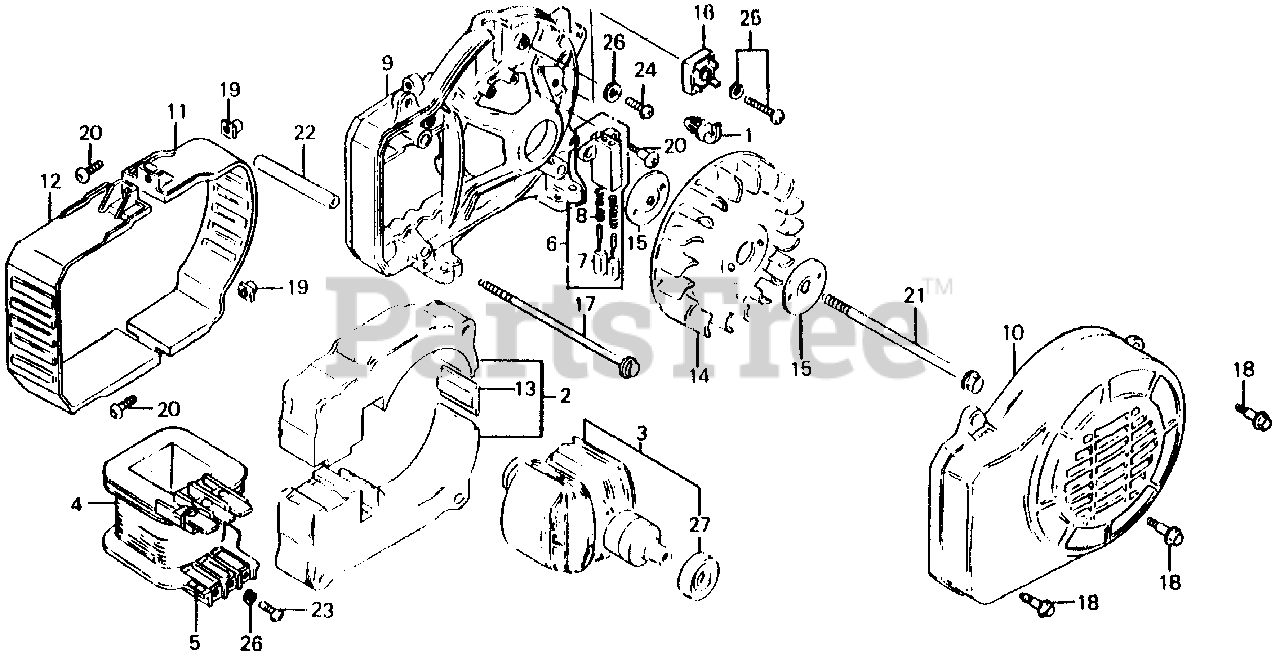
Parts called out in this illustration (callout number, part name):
1	CLAMP, D.C. CABLE
2	CORE SET, STATOR (NOT AVAILABLE)
4	BOBBIN, STATOR COIL (NOT AVAILABLE)
5	MARK, WIRE COLOR
6	HOLDER ASSY., BRUSH
8	SPRING, BRUSH
9	HOUSING, RR. (NOT AVAILABLE)
10	COVER, GENERATOR END
11	COVER, R. STATOR
12	COVER, L. STATOR
13	STIFFENER, STATOR
14	FAN, COOLING
15	PLATE, FAN
16	DIODE, D.C.
17	BOLT, FLANGE (6X116)
18	BOLT, GENERATOR END COVER
19	NUT, SPECIAL (5MM)
20	BOLT, STATOR COVER SETTING
21	BOLT, FLANGE (8X154)
22	PIN, DOWEL (11X100)
23	SCREW, PAN (5X6)
24	SCREW, PAN (5X12)
25	SCREW-WASHER (4X18)
26	WASHER, SPRING (5MM)
27	BEARING, RADIAL BALL (6203UU)
